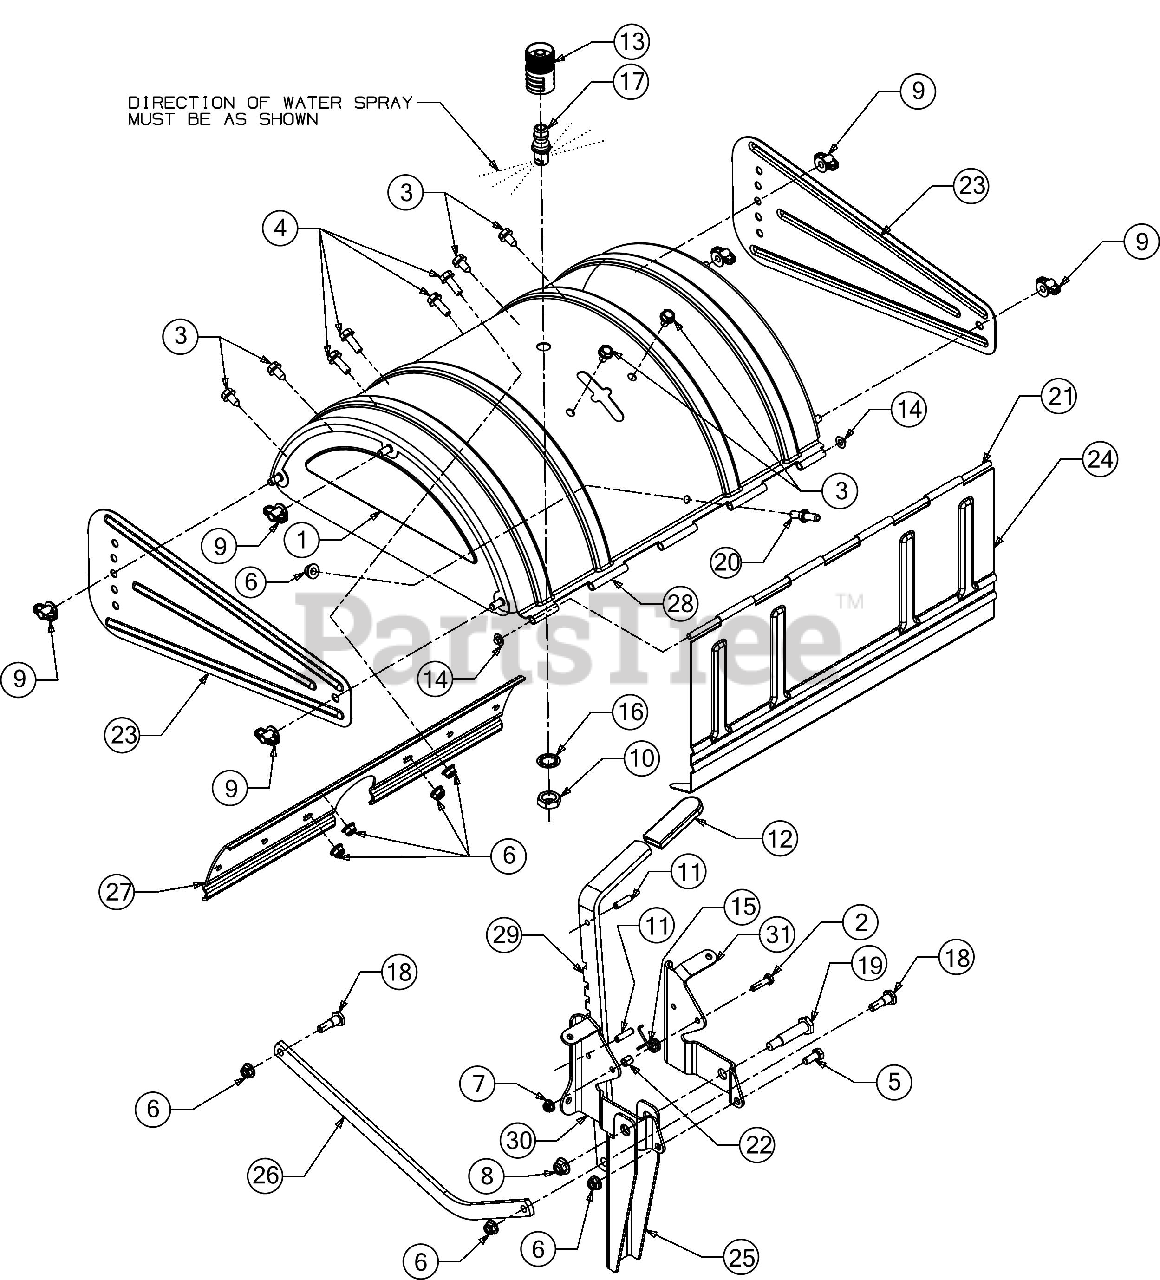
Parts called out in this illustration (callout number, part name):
1	END COVER ASSEMBLY
1	CLINCH STUD 5/16-18 x .75
2	SCREW 1/4-20 X1.00 GR5
3	SCREW 5/16-18 x .625
4	SCREW 5/16-18 x .875 GR5
5	SCREW 5/16-18 x .75 GR5
6	FLANGE LOCK NUT 5/16-18
7	FLANGE LOCK NUT
9	WING NUT 5/16-18
10	HEX NUT
11	SPRING PIN 1/4 x 1.00
12	DEPTH BAR HANDLE GRIP
13	WATER NOZZLE
14	PUSH NUT
15	TORSION SPRING
16	LOCK WASHER 5/8
17	DECK WASH NOZZLE
18	SHOULDER SCREW
19	SHOULDER BOLT .498 x 1.635:3/8-16
20	SHOULDER SCREW
21	TILLER FLAP ROD
22	ROUND SPACER
24	REAR TINE SHIELD
25	REVERSE STOP ARM
26	DEPTH DRAG BAR
29	DEPTH ADJUSTMENT BRACKET
30	TAIL BRACKET (LH)
31	TAIL BRACKET (RH)
